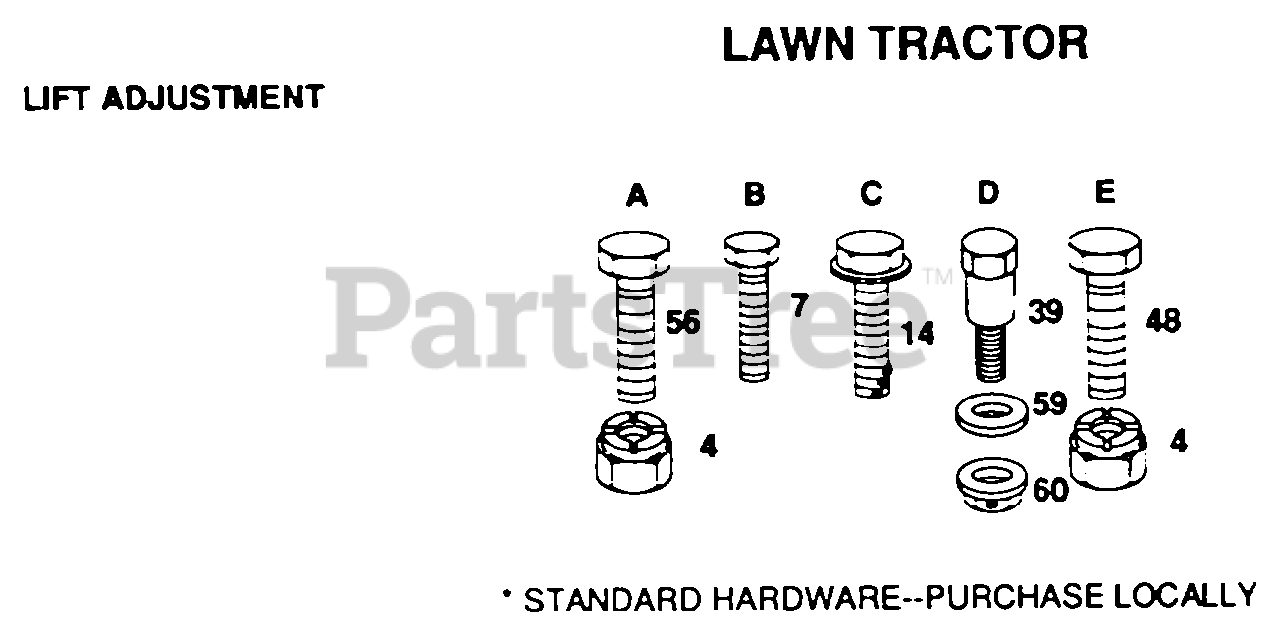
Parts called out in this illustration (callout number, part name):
7	SCREW
14	SCREW
39	"BOLT, SHOULDER LT"
56	BOLT
59	WASHER T
60	NUT SPECIAL T
